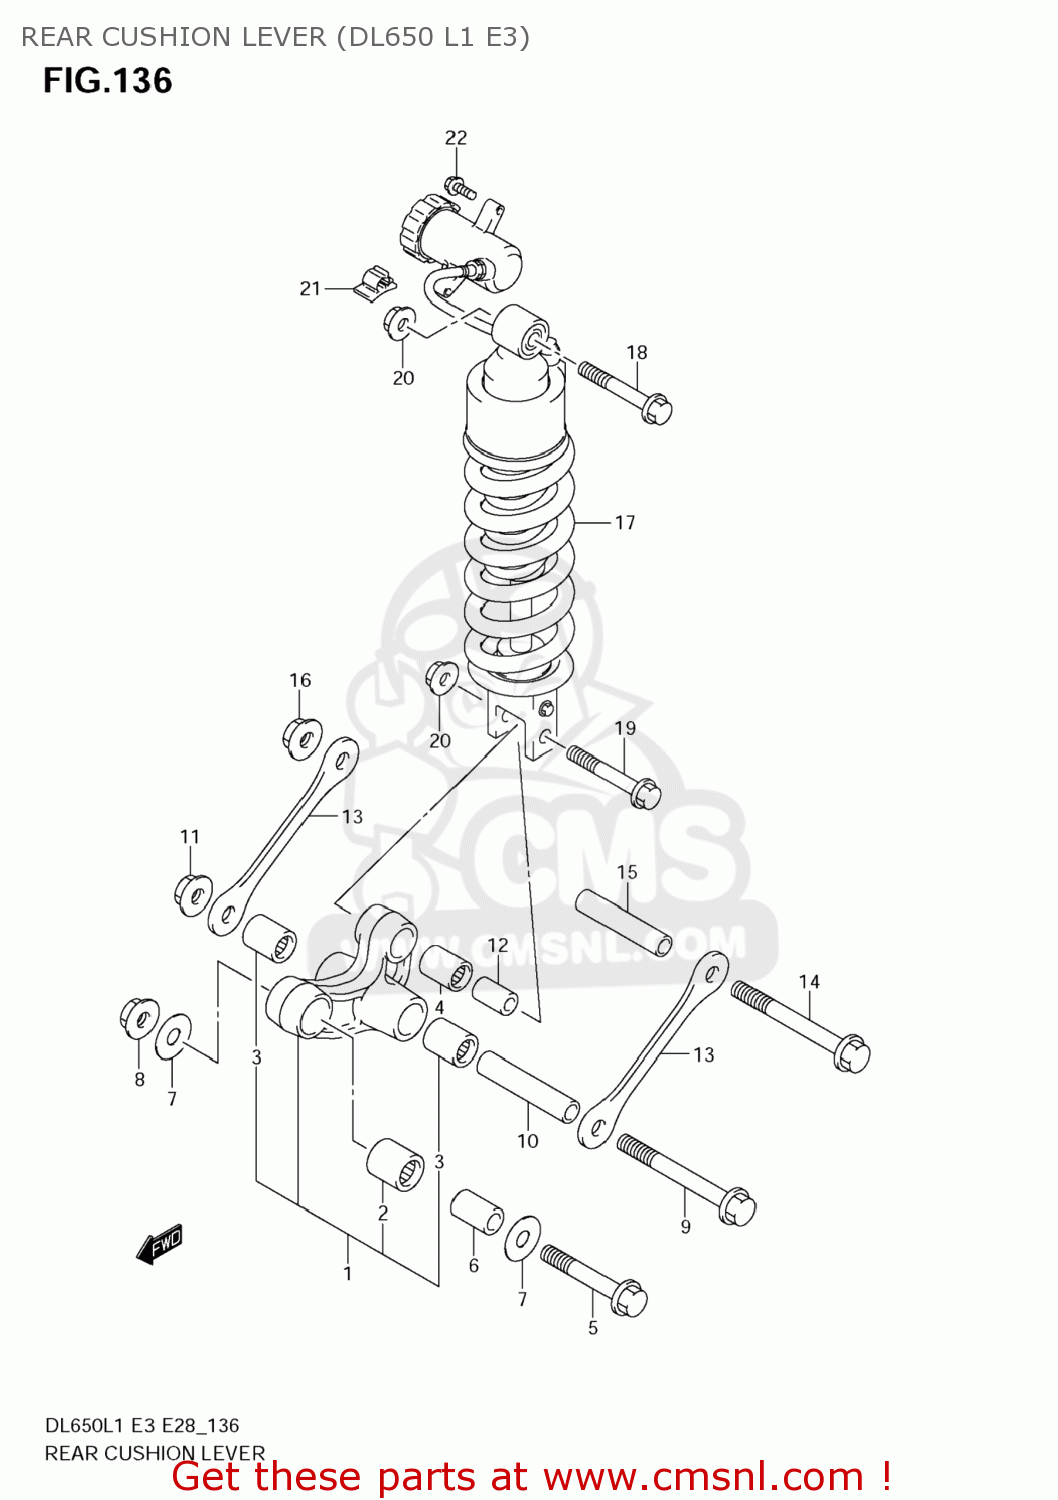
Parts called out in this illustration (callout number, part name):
1	LEVER SET,RR CUSHION
2	BEARING(20X27X30)
3	BEARING(17X24X25)
4	BEARING(17X24X26)
5	BOLT,RR CUSHION LEVER FR
6	SPACER,RR CUSHION LEVER FR
7	WASHER(12X34X1)
8	NUT
9	BOLT,RR CUSHION ROD
10	SPACER(12X17X85)
11	NUT
12	SPACER,RR CUSHION LEVER
13	ROD,RR CUSHION LEVER
14	BOLT,RR CUSHION ROD
15	SPACER(12X17X85)
16	NUT
17	ABSORBER ASSY,RR SHOCK(SILVER)
18	BOLT(10X70)
19	BOLT(10X55)
20	NUT
21	CLAMP
22	BOLT
